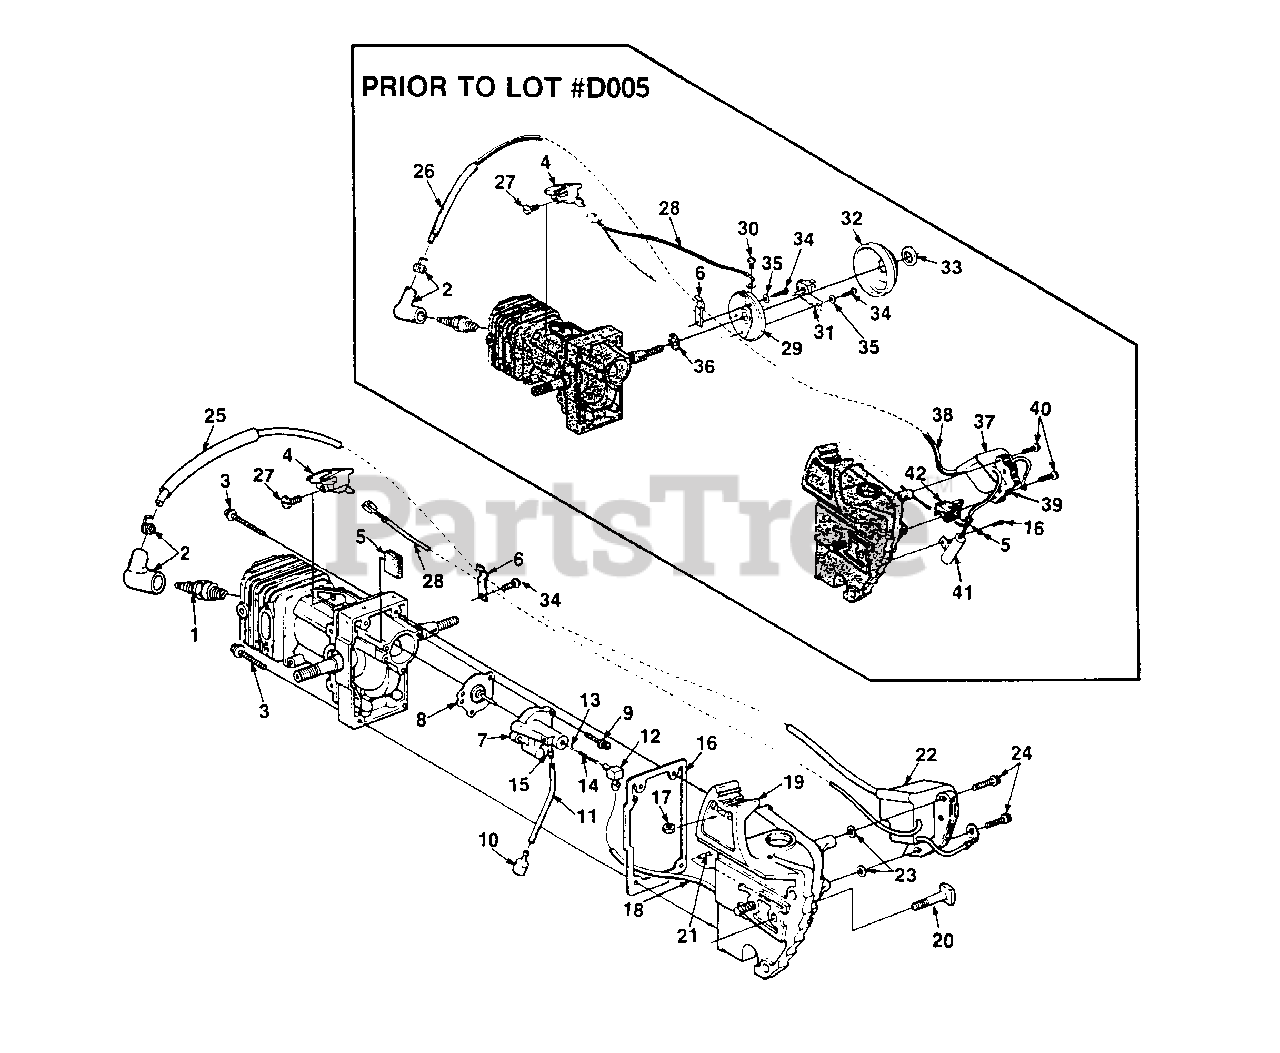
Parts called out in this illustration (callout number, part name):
1	SPARK PLUG
2	TERMINAL- Spark plug
3	SCREW- Hex washer hd. 8-32 x 1.25
4	BUSHING & TERMINAL
5	COVER- Vent
6	CLAMP- High tension lead
7	PUMP- Automatic oil
8	PLUNGER- Oil pump
9	SCREW- 8-32 x .625
10	FILTER- Oil
11	LINE- Oil pick-up 2 1/4"
12	FITTING- Tube
13	BALL- Check friction
14	SPRING- Choke valve
15	FITTING- Tube
16	GASKET- Oil tank
17	NUT- Hex centerlock 10-24
18	RUBBER- Tubing 4 3/4
19	TANK- Oil
20	BOLT- Guide bar
21	FITTING- Tube
22	KIT- Ignition conversion
23	WASHER- Flat
24	SCREW- Mach
25	SLEEVE- Insulating
26	SLEEVE- Wire (fiberglass)
27	SCREW- Pan hd., plastite (6 x 1/4)
28	LEAD- Stop switch
29	BOX- Breaker
30	SCREW- Plastite #6 x 1/4
31	POINTS- Breaker
32	COVER- Breaker box
33	SEAL- Breaker box cover
34	SCREW- Pan washer hd., 6-32 x 3/8
35	WASHER- Flat #8
37	COIL- Ignition
38	LEAD- Hi-tension
39	CORE
40	SCREW- Hex hd. 8-32 x 3/4
41	CONDENSER
42	BLOCK- Terminal
